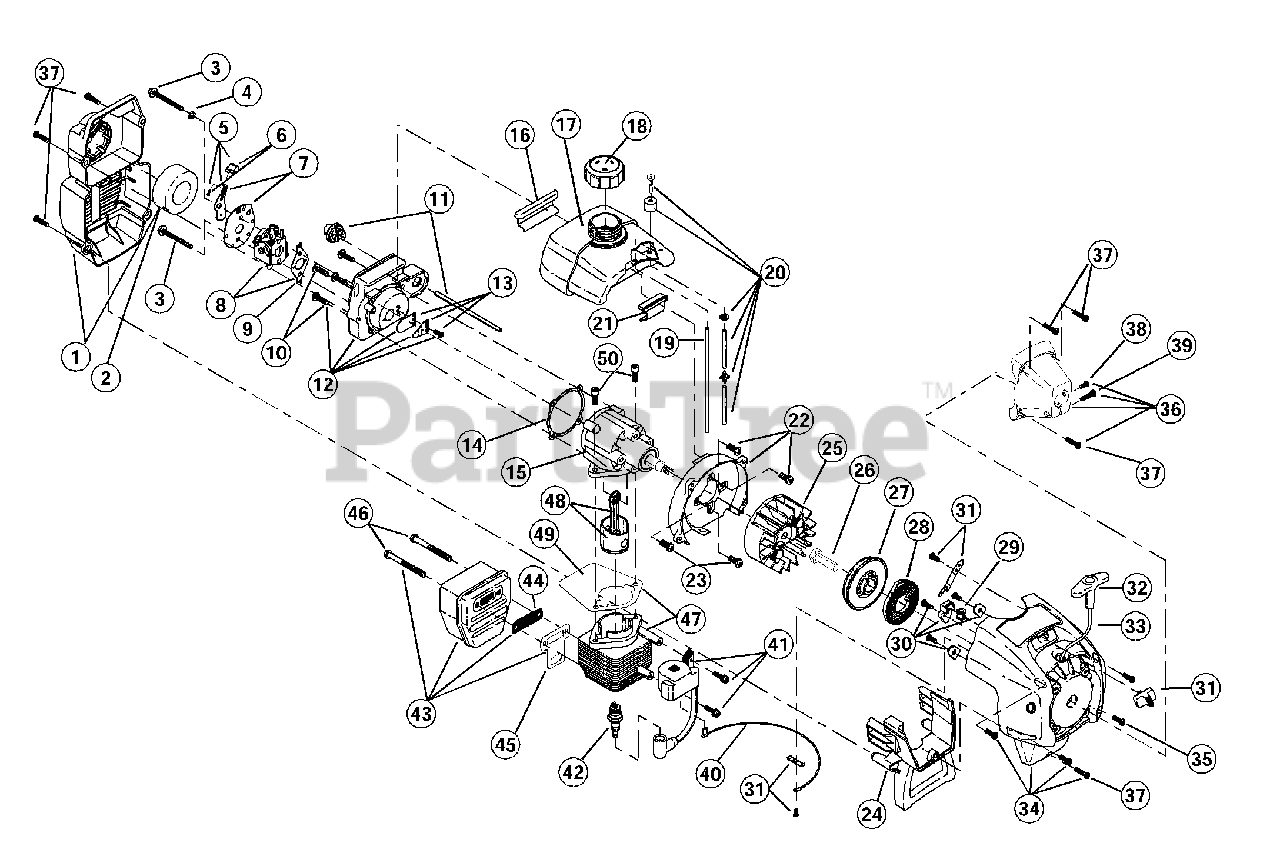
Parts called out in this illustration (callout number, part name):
1	Air Cleaner/Muffler Cover Assembly
2	Air Cleaner Filter
3	Carburetor Mounting Screw Assembly
4	Wavey Washer
5	Choke Lever Assembly
6	Choke Knob and Screw
7	Choke Lever and Plate
8	Carburetor Assembly
9	Carburetor Gasket
10	Carb Mount Screw
11	Primer and Hose Assembly
12	Carb Mount Assembly
13	Reed Assembly
14	Carburetor Mount Gasket
15	Crank Case Service Assembly
16	Rear Mounting Pad
17	Fuel Tank Assembly
18	Fuel Cap Assembly
19	Fuel Return Line
20	Fuel Line Assembly
21	Front Mounting Pad
22	Shroud Assembly
23	Shroud Screw
24	Shroud Extension & Stand
25	Flywheel Assembly
27	Recoil Pulley Assembly
28	Recoil Spring
29	Rope Guide
30	Pulley Retainer Assembly
31	Switch Assembly
32	Pull Handle
34	Starter Housing Assembly
35	Housing Screw
36	Clutch Cover Assembly
37	Cover Screw
38	Anti-Rotation Screw
39	Clamping Screw
40	Wire Lead
41	Module Assembly
42	Spark Plug
43	Muffler Assembly
44	Spark Arrestor Screen
45	Exhaust Gasket
46	Muffler Mounting Bolt Assembly
47	Cylinder Assembly
48	Piston and Rod Assembly
49	Cylinder Gasket
50	Cylinder Bolt
